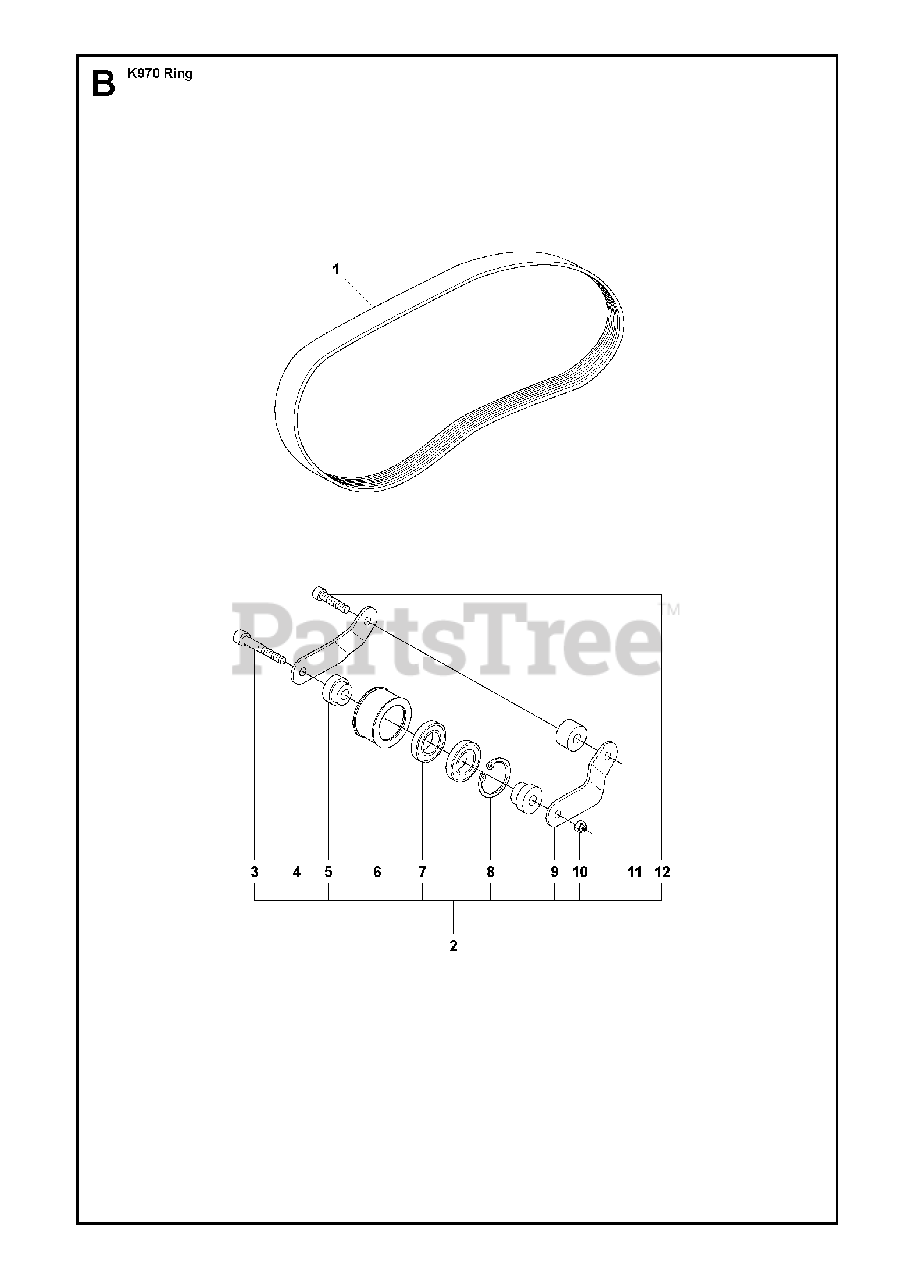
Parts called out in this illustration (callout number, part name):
2	BELT TENSIONER ASSYIncl. 3 - 12
3	SCREW ITXSCM
7	BALL BEARING
10	NUT
12	SCREW ITXSCM
